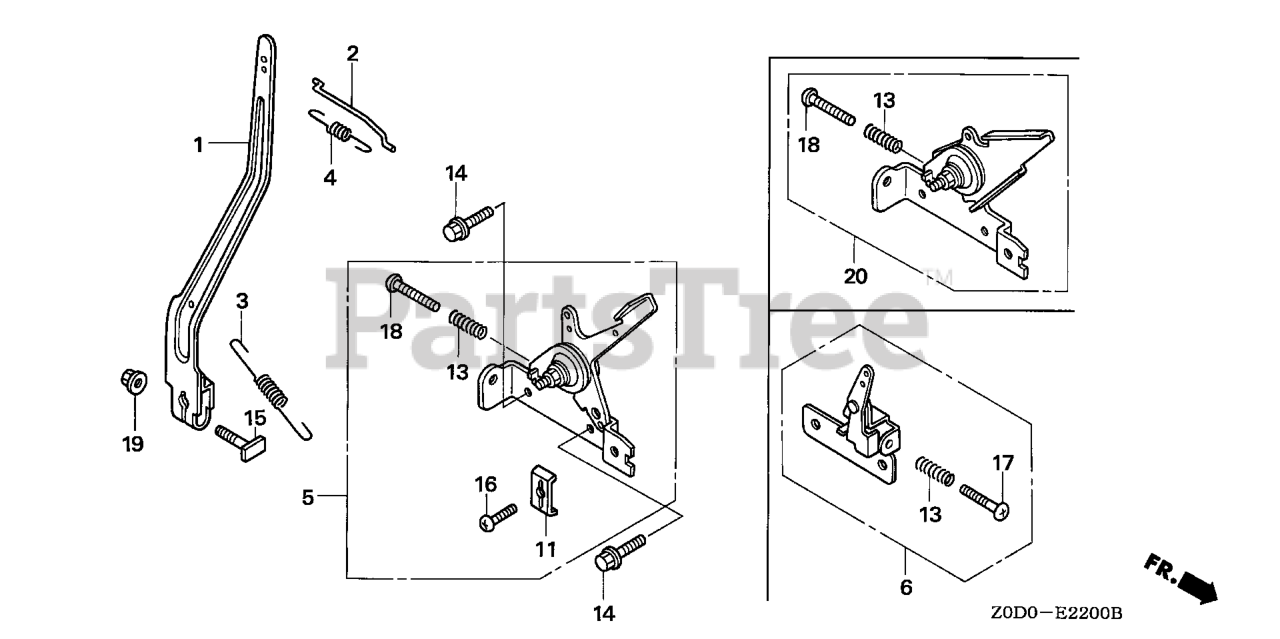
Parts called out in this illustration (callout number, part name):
1	ARM, GOVERNOR
2	ROD, GOVERNOR
3	SPRING, GOVERNOR
4	SPRING, THROTTLE RETURN
5	CONTROL ASSY. (STD)
11	HOLDER, CABLE
13	SPRING, CONTROL ADJUSTING Use from Engine SN 2327377.
14	BOLT, FLANGE (6X14)
15	BOLT, GOVERNOR ARM
16	SCREW, PAN (5X16)
18	SCREW, PAN (5X25)
19	NUT, FLANGE (6MM)
